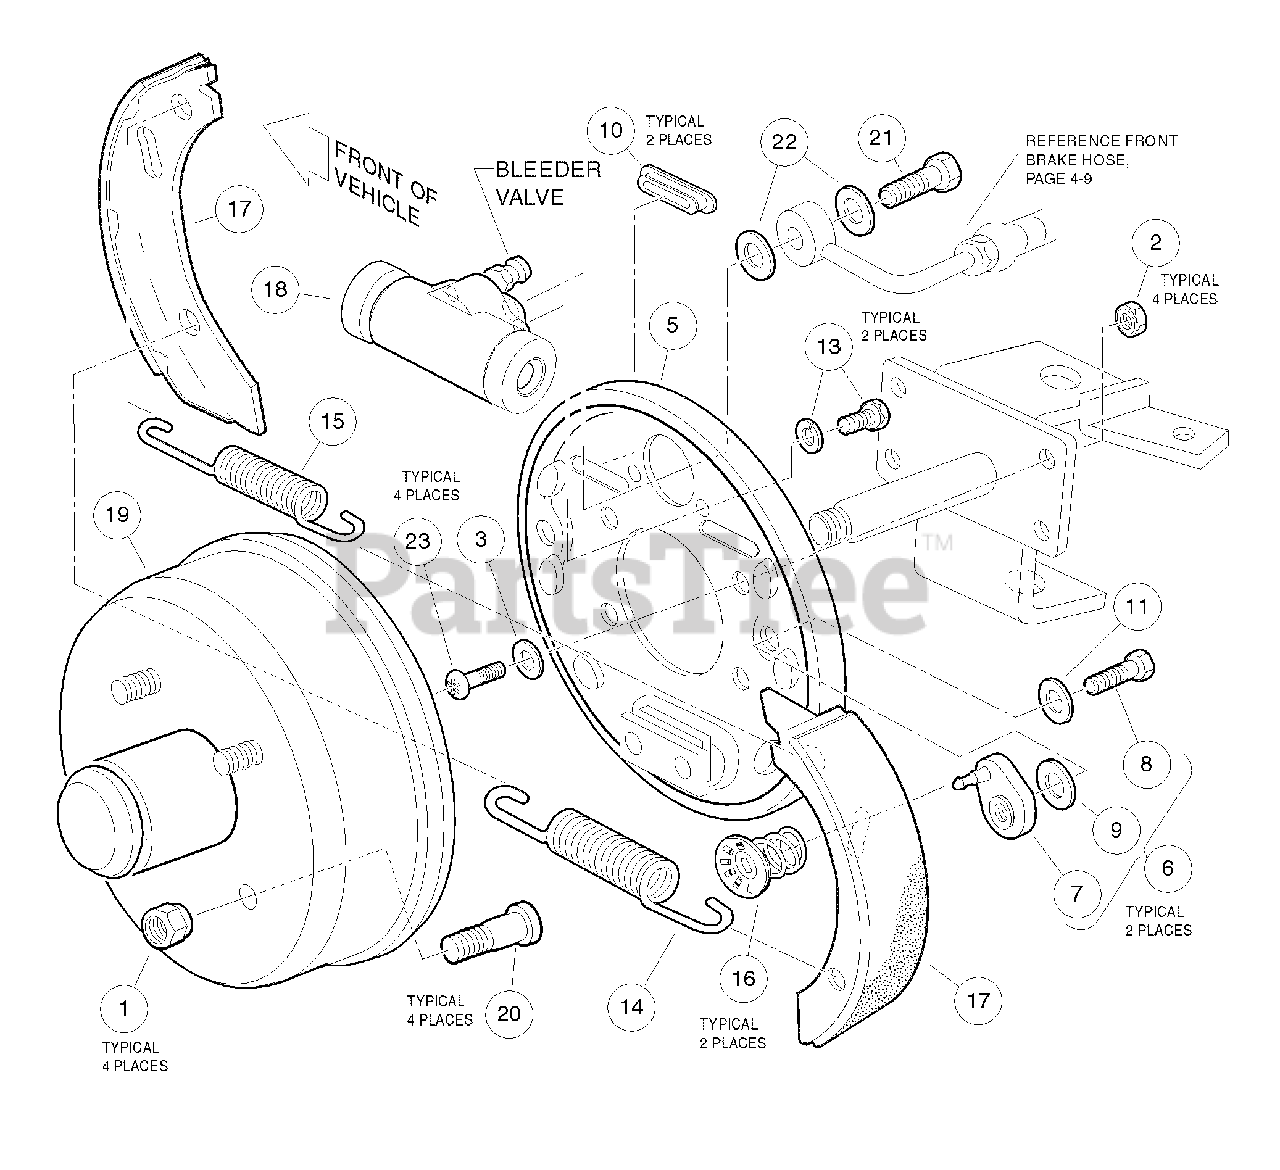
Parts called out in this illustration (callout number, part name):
1	500-20 Unf Lug Nut
2	Nut, 5/16-24 Hex Head Cone
3	Washer, 5/16 Hardened
4	Cluster, Front Brake
5	Backing Plate Asm
6	Kit, Axle Adjuster
8	Bolt, 1/4-28 UNF X 31
10	Dust Cover
11	Washer, 1/4 Flat
12	Kit, Axle Hardware
13	Bolt, Wheel Cylinder
14	Spring, Shoe To Shoe, Lower
15	Spring, Shoe To Shoe, Upper
16	Shoe Hold Down
17	Shoe Kit, Axle Set
18	Wheel Cylinder Assembly 0625 Dia
19	Assembly, Front Hub
21	Bolt, Banjo
22	Copper Washer
23	Screw, 5/16-24 X 10 Torx Hd
